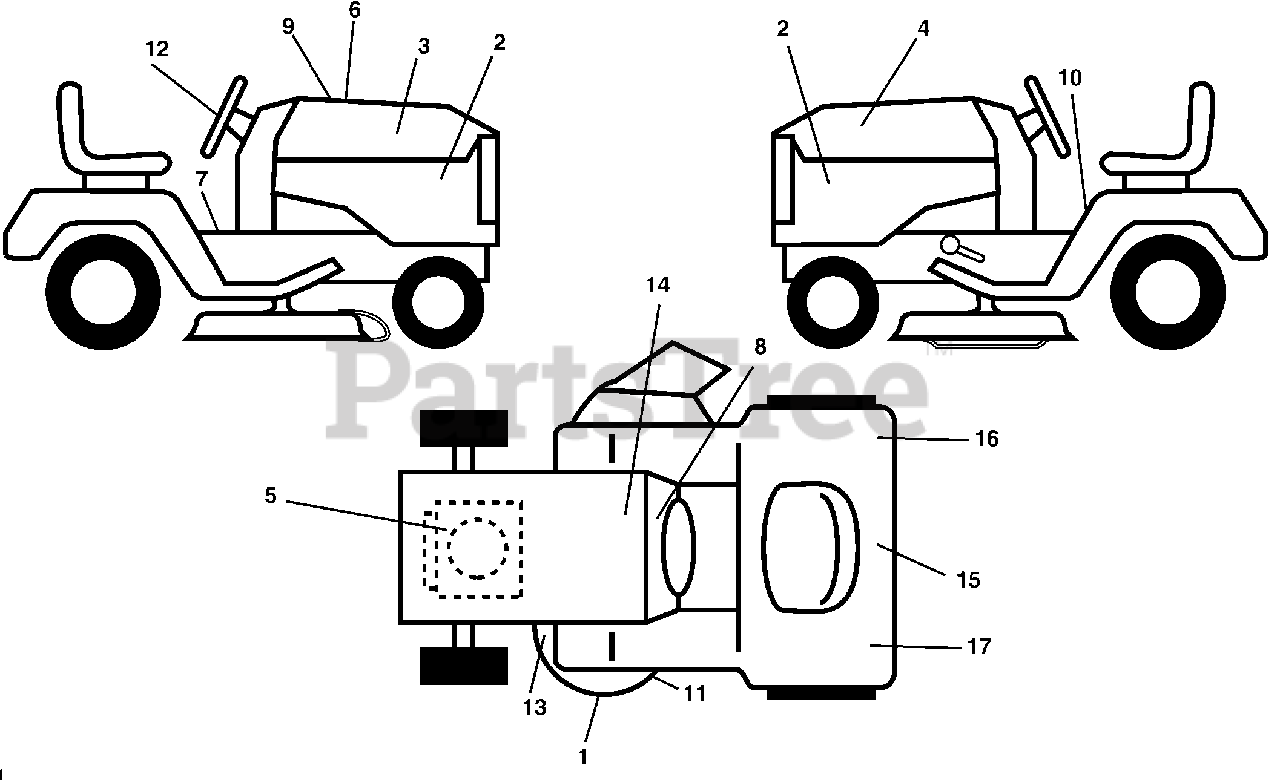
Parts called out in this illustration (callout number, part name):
1	Decal Deck Hvy Duty
2	Decal Panel Side
3	Decal Hood RH
4	Decal Hood LH
5	Decal HP Engine
6	Decal Hood Cust. Resp.
7	Decal Operator
8	Decal Dash
9	Decal Replacement
10	Decal Fender Danger
11	Decal V-Belt Sch.
12	Decal Wheel Steering
13	Decal Deck Caution
14	Decal Bat Dan/Psn
15	Decal Fender
16	Decal Reflector RH
17	Decal Reflector LH
